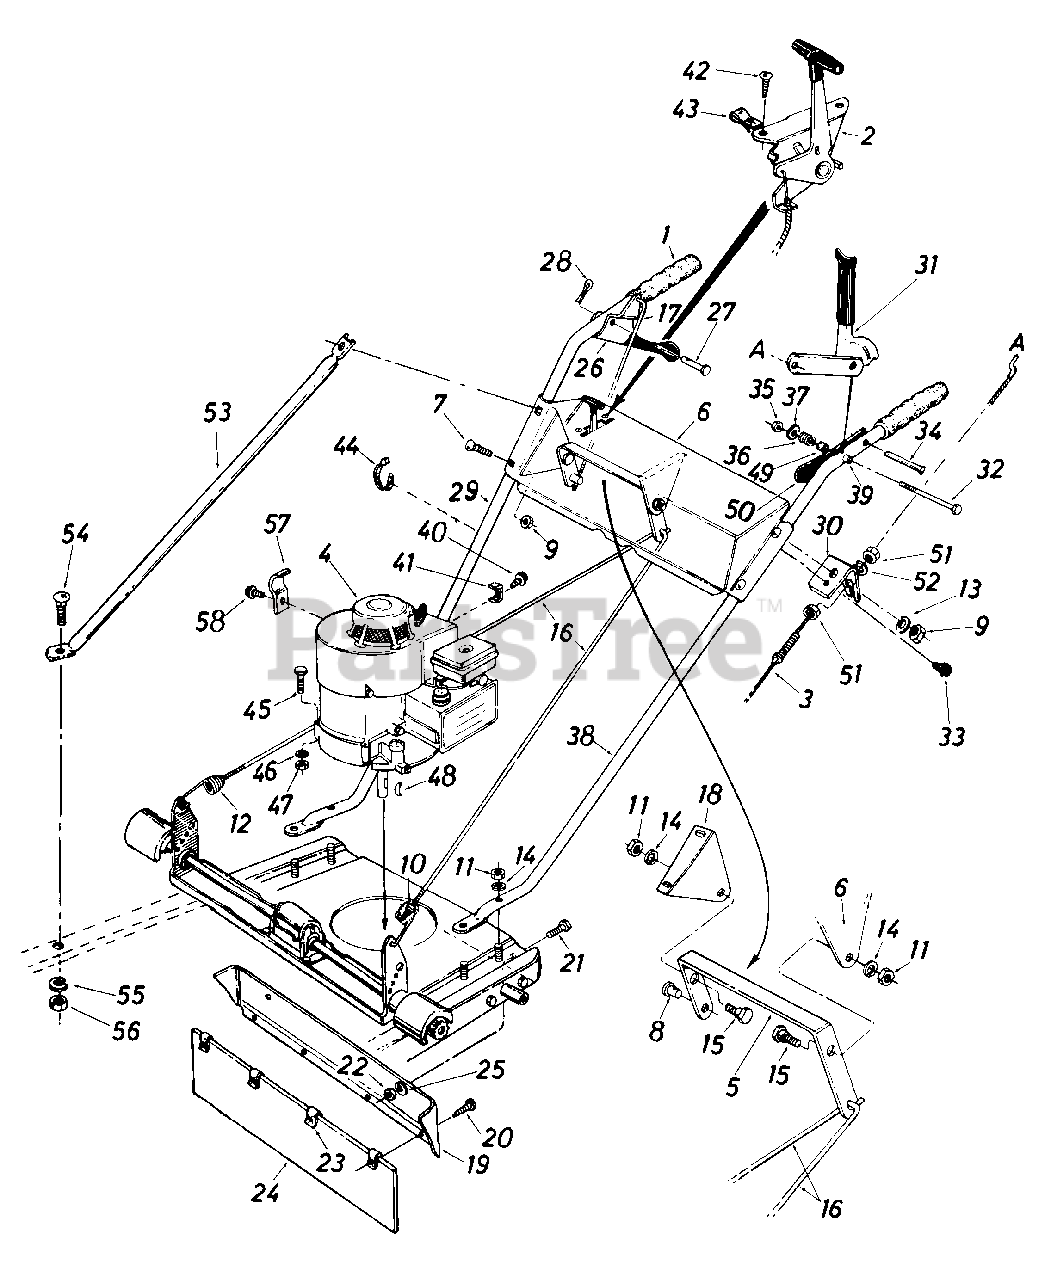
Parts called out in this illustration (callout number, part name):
1	Grip - Black
2	Throttle Control Ass'y. - Comp.
3	Clutch Cable - 56" Long
4	Engine
5	Link Bracket
6	Handle Panel Ass'y.
7	Carriage Bolt 5/16-18 x 1.75" Lg.
8	Adj. Ferrule 1/4-20 Thd.
9	Hex Nut 5/16-18 Thd.
10	Hex Ins. L-Nut 1/4-20 Thd.
11	Hex Nut 3/8-16 Thd.
12	Extension Spring
13	L-Wash. 5/16" I.D.
14	L-Wash. 3/8" I.D.
15	Shld. Bolt .500" Dia. x .295
16	Lockout Rod
17	Rod .214" Dia. x 14.38" Lg.
18	Bracket
19	Drag Shield Adapter
20	Hex B-Tap Scr. #10 x .62" Lg
21	Hex Bolt 1/4-28 x .62" Lg.
22	Hex Nut 1/4-28 Thd.
23	Speed Nut 102 U-Type
24	Drag Shield 4.65" x 20.0" Lg.
25	L-Wash. 1/4" I.D.
26	Clutch Grip Ass'y.
27	Clevis Pin .375" Dia.
28	Intern. Cot. Pin 5/16" Dia.
29	R.H. Handle
30	Clutch Cable Brk't.
31	Blade Clutch Grip Ass'y.
32	Hex Bolt 1/4-20 x 2.25" Lg.
33	Hex Wash. S-Tap Scr. 1/4-20 x .50" Lg.
34	Lock Pin
35	Hex Cent. L-Nut 1/4-20 Thd.
36	Compression Spring .50" O.D. x .50" Lg.
37	Internal Tooth L-Wash.
38	L.H. Handle
39	Spacer .255" I.D.
40	Hex B-Tap Scr. #10 x .38" Lg
41	Casing Clamp
42	Hex Wash. Hd. AB-Tap Scr. #10 x .50" Lg.
43	Speed Nut 10Z
44	Cable Tie Self Clinching
45	Hex Bolt 5/16-24 x 1.25" Lg.
46	L-Wash. 5/16" I.D.
47	Hex Nut 5/16-24 Thd.
48	#6 Hi-Pro Key 5/32 x 5/8" Dia.
49	Spacer .255" I.D. x .375" O.D.
50	Lock Spring
51	Hex Jam Nut 5/16-24 Thd.
52	L-Wash. 5/16" I.D.
54	Carriage Bolt 5/16-18 x .62" Lg.
55	L-Wash. 5/16" I.D.
56	Hex Nut 5/16-18 Thd.
57	Casing Clamp
58	Hex Wash. Hd. Tap Scr. #10 x .50" Lg.
